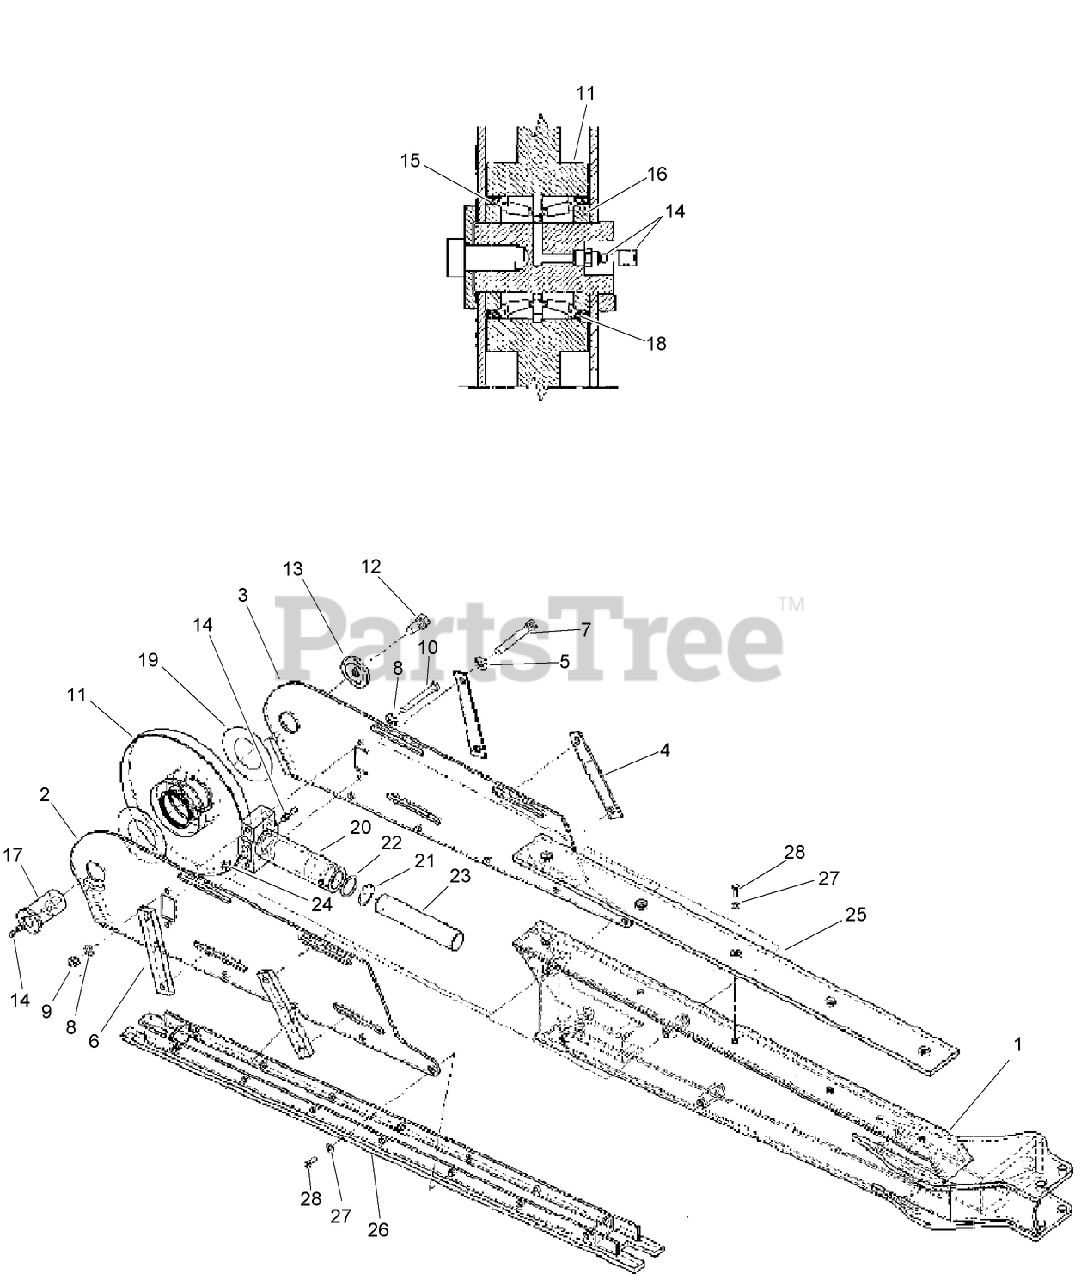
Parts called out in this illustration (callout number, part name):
1	BOOM-rock, 5 foot, direct drive trencher
2	PLATE-rock boom end, right-hand
3	PLATE-rock boom end, left hand
4	BAR-Clamp
5	WASHER-LOCK
6	BAR-Tapped
9	NUT-HEX
10	BOLT-hex, 1/2 NC x 4-1/4 inch
11	BOLLER-Boom End
14	FITTING-LUBE, STRAIGHT
15	SEAL-ROLLER
16	SPACER-bearing
17	PIN-BOOM
18	BEARING KIT
19	WASHER-BOOM, END (ROLLER)
20	CYLINDER-Boom End
21	WASHER-BACKUP
22	O-RING
23	ROD-BOOM, END (CYLINDER)
24	PLUG-BLEED
25	BAR-Wear Pad, Upper, 4\ Boom
26	CHANNEL-wear pad, lower
27	WASHER-3/8 HT
28	SCREW-HH
